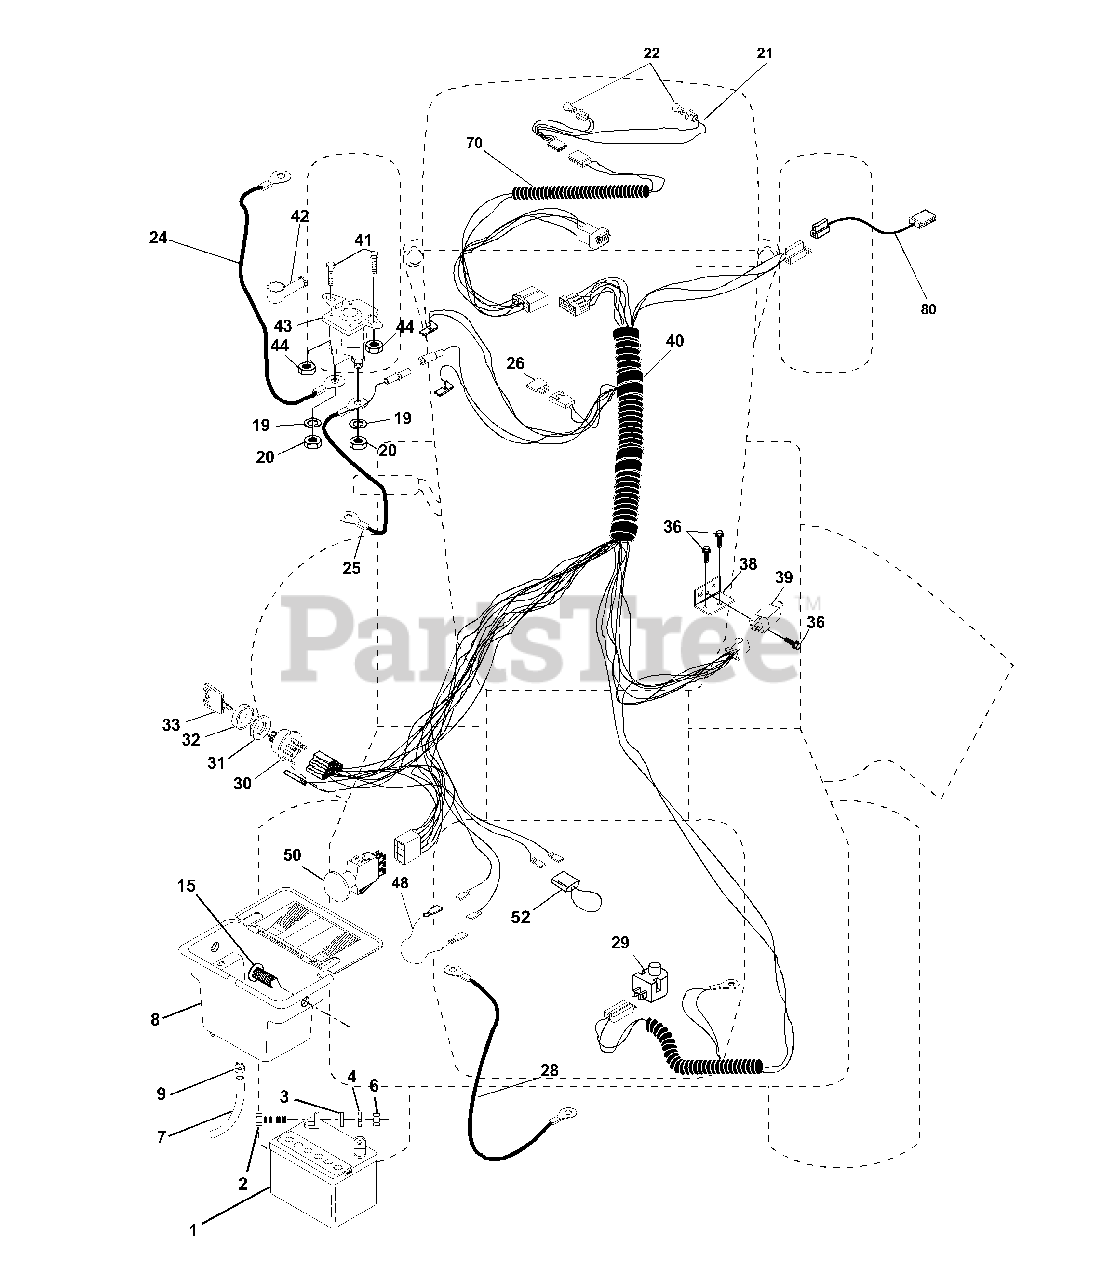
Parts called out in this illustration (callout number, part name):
1	Battery 12 Volt 25 AMP
2	Bolt Hex Hd 1/4-20unc X 3/4
3	Washer 9/32 X 5/8 X 16 Ga.
4	Washer Lock Hvy Helical 1/4
6	Nut Fin Hex 1/4-20 Unc
7	Tube Plastic 12"
8	Case Battery w/2 Holes W BRTY
9	Clamp Hose Olive
15	Fastener Snap-In
19	Washer Lock 1/4
20	Nut Jam Hex 1/4-20 Unc
21	Harness Asm Light W/4152j
22	Bulb Light #1156
24	Cable Battery 6 Ga 11" red
25	Cable Battery 6 Ga 44" w/16W
26	Fuse 30 AMP Auto Green
28	Cable Ground 6 Ga 12" black
29	Switch Plunger Nc Gray
30	Switch Ign 4 pos w/lights
31	Nut Ignition
32	Cover Sw Ignition
33	Key Ign Modleded Generic
36	Screw Tap Hex #10-24unc X 1/2
38	Bracket, Switch, Interlock
39	Switch Intlk Clutch Red 4 Term
40	Harness Ign. Elec. HMLT P/L
41	Bolt Blk Fin Hex 1/4 - 20 x 1/2
42	Cover Terminal Red
43	Solenoid
44	Nut Keps Hex 1/4-20 Unc
48	Adapter Ammeter Rectangular
50	Switch PTO 3 PTD Black
52	Protection Wire Loop
70	Harness, Eng.
80	Harness Clutch EVX
